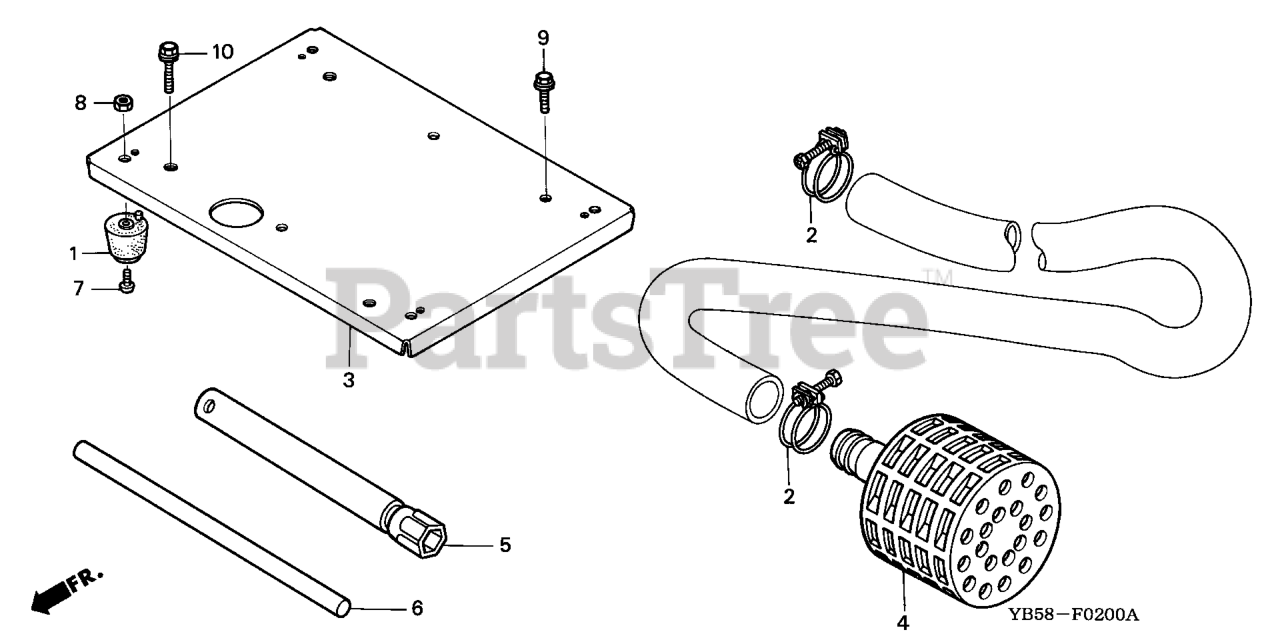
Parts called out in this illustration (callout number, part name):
1	RUBBER (LOWER) Use up to Frame SN 1382074.
2	BAND, HOSE
3	BED, FRAME
4	STRAINER Use from Frame SN 1582886.
5	WRENCH, SPARK PLUG
6	HANDLE, BOX WRENCH (NOT AVAILABLE)
7	SCREW, PAN (6X10)
8	NUT, HEX. (6MM)
9	BOLT, FLANGE (8X25)
10	BOLT, FLANGE (8X28)
